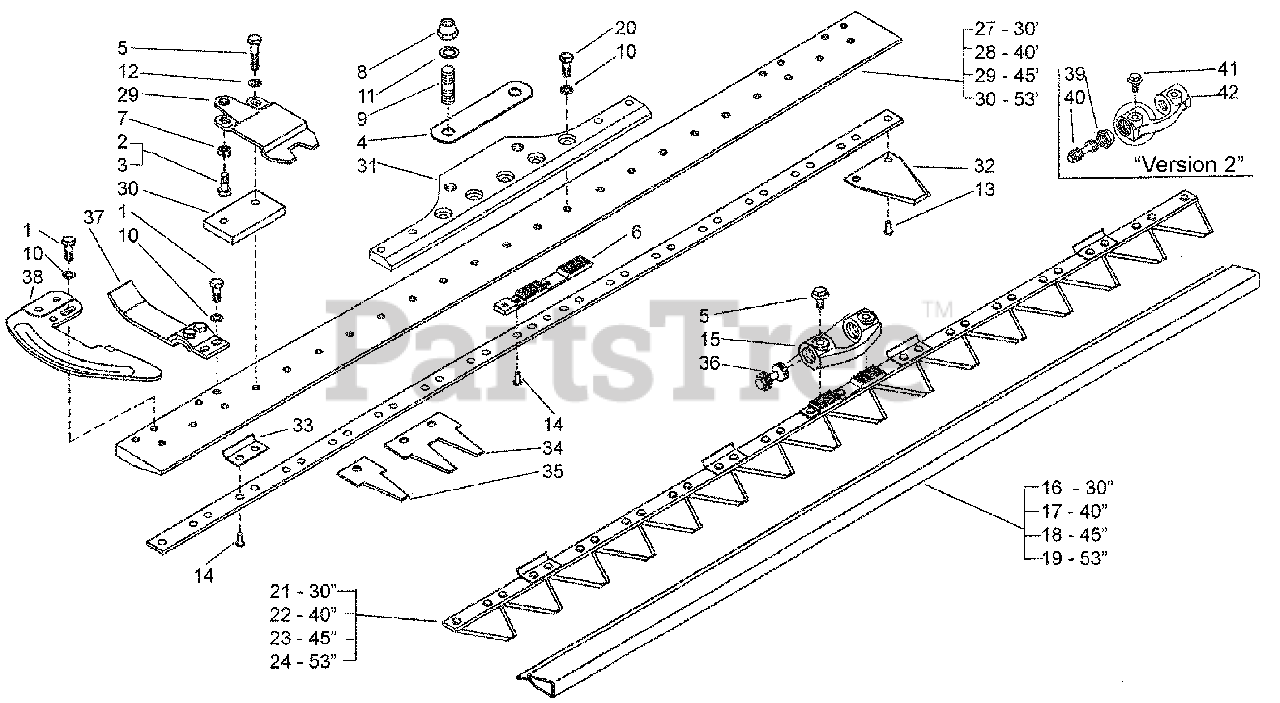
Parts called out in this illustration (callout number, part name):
1	SCREW, M8X16
2	SCREW, M8X20
3	SCREW, M8X25
4	SPACER PLATE
5	SCREW, M8X35
6	MOUNTING PLATE
8	SPECIAL NUT, M14
9	STUD, M14X1.5X44
10	SUPER WASHER, M8
11	SUPER WASHER, M14
12	WASHER, LOCK, M8
13	RIVET M6.5X13
14	RIVET M6.5X16
15	BLADE COUPLER
16	BLADE GUARD 30"
17	BLADE GUARD 40"
18	BLADE GUARD 45"
19	BLADE GUARD 53"
21	BLADE ASSEMBLY, SERAT
22	BLADE ASSEMBLY, SERAT
23	BLADE ASSEMBLY, SERAT
24	BLADE ASSEMBLY, SERAT
25	SLIDE FOR CUTTER BAR
26	SLIDE FOR CUTTER BAR
27	SLIDE FOR CUTTER BAR
28	SLIDE FOR CUTTER BAR
29	BLADE HOLDER
30	BLADE GUIDE BLOCK
31	BAR COUPLING
32	INDIVIDUAL BLADE, SERATED
34	DOUBLE FINGER
35	SINGLE FINGER
